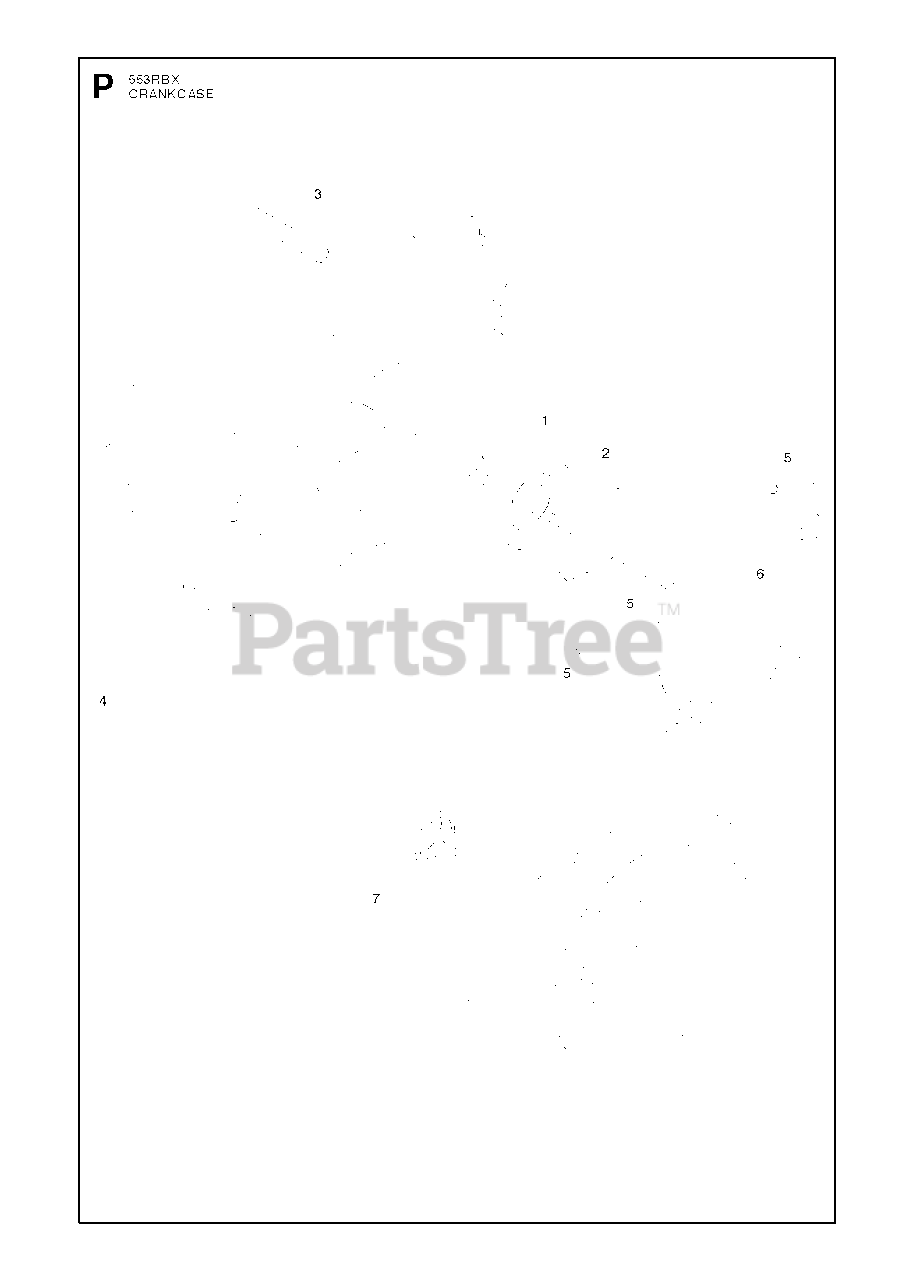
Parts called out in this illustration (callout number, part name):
3	BOLT
4	CRANKCASE COMP
5	PIN
6	GASKET, CASE
